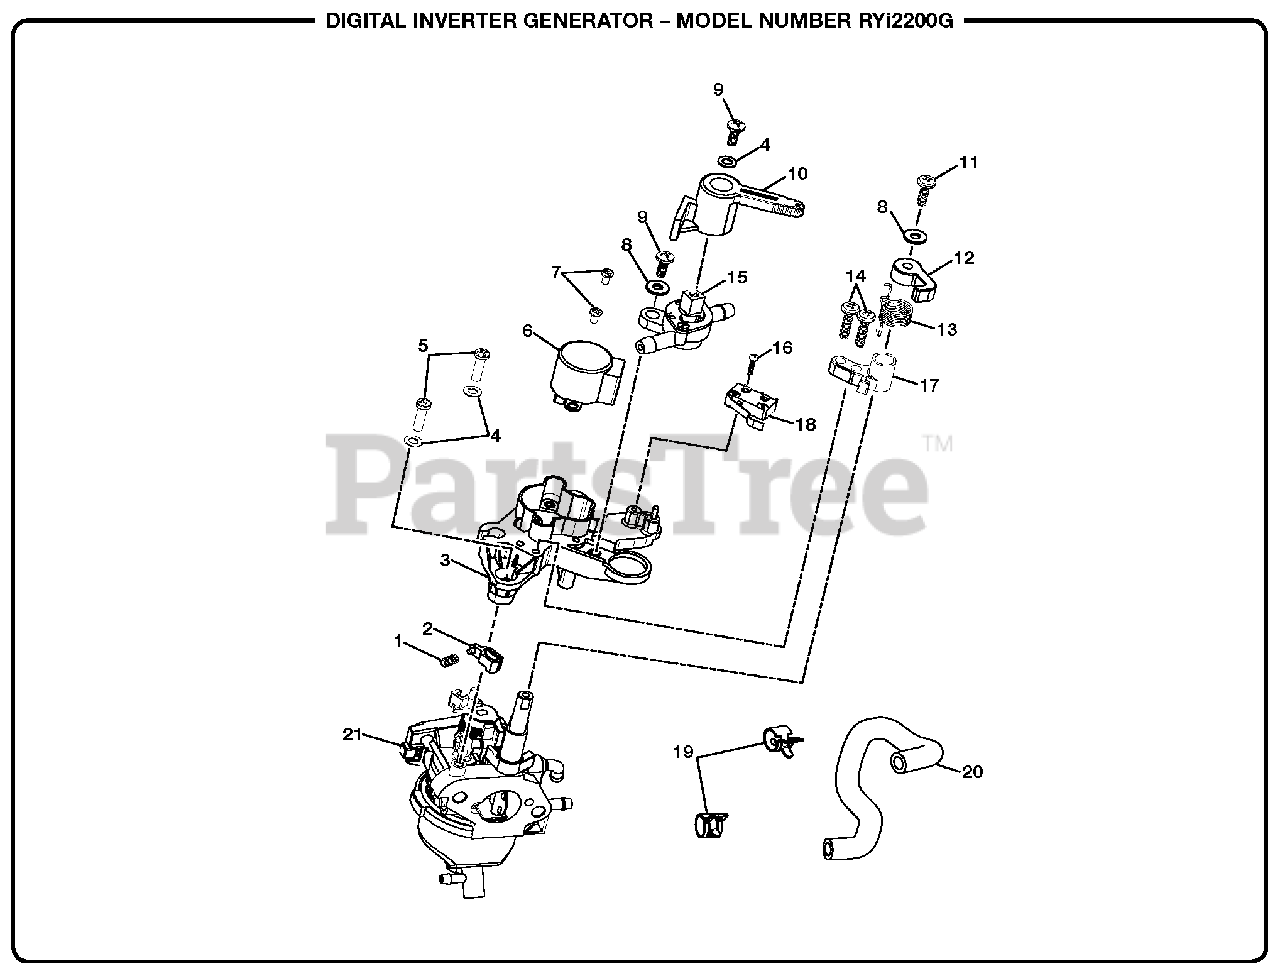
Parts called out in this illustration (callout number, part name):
1	Governor Damping Spring
2	Governor Joint
3	Governor Motor Bottom Housing
4	Washer (M4)
5	Screw (M4 x 14 mm, Phillips Pan Hd.)
7	Screw (M3 x 5 mm, Phillips Pan Hd.)
8	Washer (OD10 x ID4.2 x 1t)
9	Screw (M4 x 10 mm, Phillips Pan Hd.)
10	Control Lever
11	Screw (ST4.2 x 12 mm, Phillips Pan Hd.)
12	Choke Lever Upper
14	Screw (ST4.2 x 16 mm, Phillips Pan Hd.)
15	Fuel Valve
16	Screw (M3 x 0.8 mm, Phillips Pan Hd.)
17	Support Bracket
18	Engine Shut-Off Switch
19	Clamp (D9 x 1.2 mm)
20	Fuel Hose (Fuel Valve To Carb)
21	Carburetor
